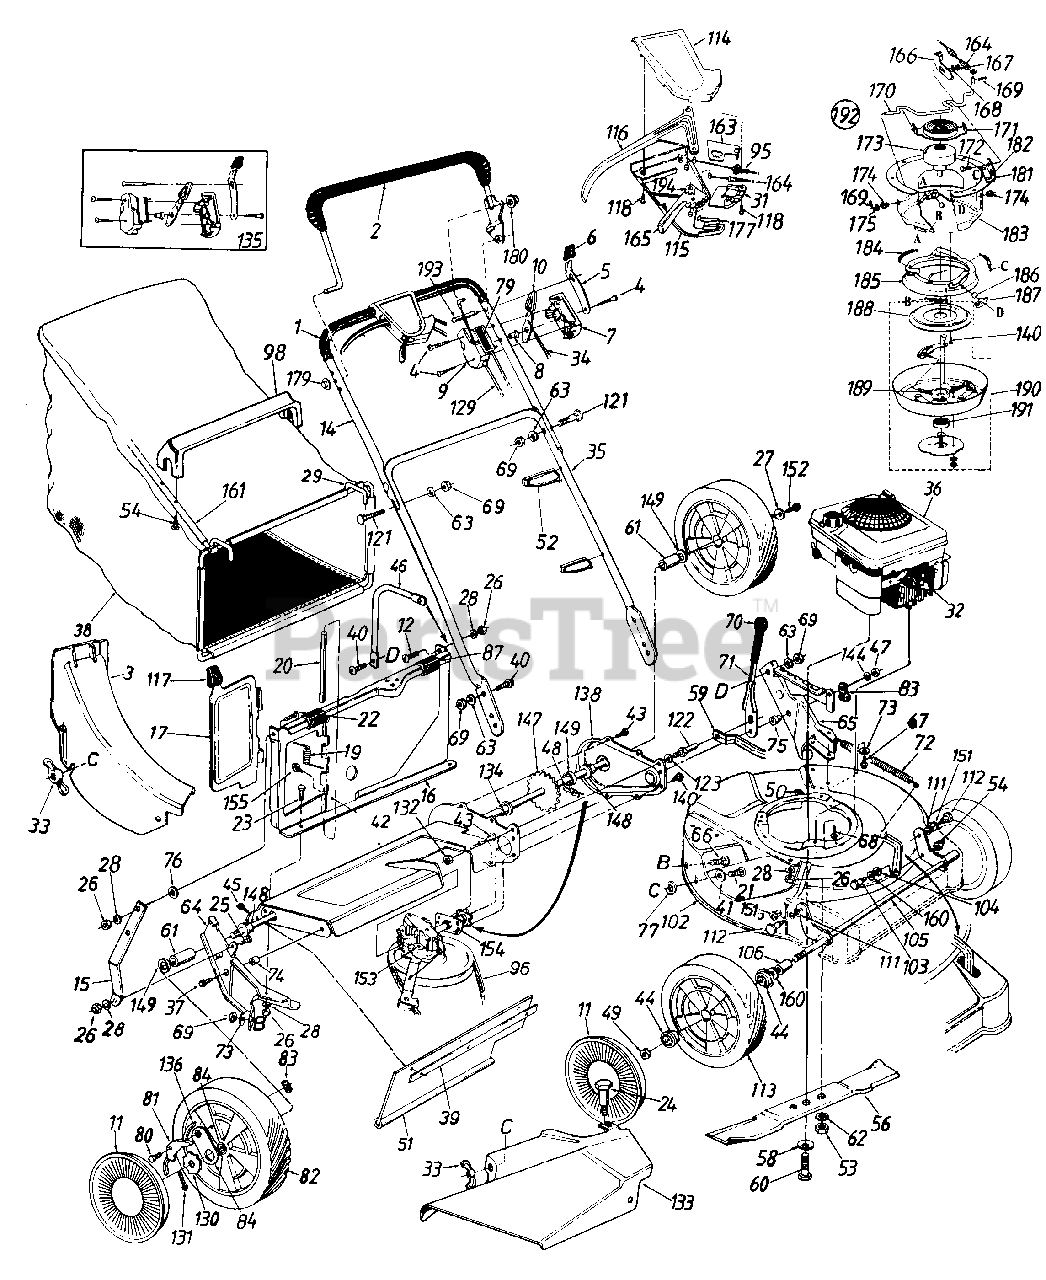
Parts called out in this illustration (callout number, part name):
1	GRIP-FOAM
3	CHUTE ASSY BLACK
4	SCREW-TRUSS MACH
5	SPRING-LOCKOUT
6	KNOB
7	PANEL HALF-CONTROL
8	PIN-CONTROL DISC
9	PANEL HALF-CLUTCH
10	LEVER-THROTTLE CONT-REV
11	HUB CAP
12	SCREW-TRUSS MACH
14	HANDLE-UPPER
19	SPRING-TORSION
21	BOLT-CARRIAGE 1/4-20 X .62
22	SCREW-TRUSS MACH
23	SCREW-HEX 1/4-20 X .50
24	SCREW-SHLD
25	SCREW-HEX 1/4-20 C .62
26	NUT-HEX 1/4-20
27	WASHER-SPRING BELL
28	LOCK WASHER 1/4 DIA
31	COVER-SP CONTROL
32	INSULATOR-SPARK PLUG
33	NUT-WING
34	WIRE-THROTTLE
35	HANDLE-LOWER PAINTED
38	BAG-GRASS-BLACK
39	STRIP-RETAINING
40	SCREW-TRUSS MACH 5/16-18 X .75
41	WASHER-FL-.344 ID X .62 OD X .033
44	BEARING-BALL
45	SCREW-HEX WASH HD
46	ARM-CATCHER SUPPORT
47	NUT-HEX LOCK 3/8-24
48	#48 CHAIN 1/2 PITCH
49	NUT-HEX INS L-1/2-20
52	TIE-CABLE
53	NUT-HEX 3/8-24
54	SCREW-HEX AB-TAP
56	BLADE-21IN
58	WASHER-BELL
59	ARM-HGT ADJ CONNECT
60	SCREW-HEX 7/16 N.F. X 2 GR.5
61	SPACER-.513 ID X .703 OD X .69
62	WASHER-LOCK-3/8
63	WASHER-LOCK-5/16
64	BRACKET ASSY-HDLE-RH
65	BRACKET ASSY-HDLE-LH
66	BOLT-CARRIAGE 5/16-18 X .62
67	SCREW-HEX WASH HD 5/16-18X1/2
69	NUT-HEX 5/16-18
71	LEVER-HGT ADJ
72	SPRING-EXTENSION
73	WASHER-BELL .337 X .867 X .057
74	SPACER
75	SPACER-SHLD .500 X .100
76	WASHER-FL-.285 ID X 1.25 OD X .060
77	RETAINER-BOLT 1/4X.50 OD
80	SCREW-SHLD .342 DIA X .268
81	PAWL
82	WHEEL ASSY W/TIRE
87	CLIP-PANEL BAG
95	CABLE-CLUTCH
96	BELT-V 3/8 X 31.0
98	HANDLE-BAG-BLACK
102	DECK ASSEMBLY-21IN
103	SCREW-SHLD .500 DIA X .295
104	WASHER-BELL .505 ID X 1.00 OD
105	AXLE ASSY
111	WASHER-INTERN L 3/8 X.56 OD X .018
112	SCREW-SHLD
113	WHEEL ASSY W/TIRE E
114	COVER-SP CONTROL-UPR
115	COVER-SP CONTROL-LWR
116	LEVER-CONTROL
117	KNOB
118	SCREW-FL C-SUNK AB
121	BOLT-CARRIAGE-CURV 5/16-18 X 1.38
122	PIN-SHLD 3/8-24X1.43 LG
123	WASHER-LOCK-3/8
129	CABLE-CLUTCH 49 IN
130	RATCHET
131	PIN-COTTER-1/8 DIA X 1.00
132	NUT-HEX JAM 3/8X24
133	DEFLECTOR-SIDE CHUTE
134	BEARING-HEX FLANGE
135	KIT-THROTTLE CONTROL
136	SPRING-NYLON
144	WASHER-FL-.385 ID X .87 OD X .06
147	SHAFT ASSY-REAR
148	BEARING-HEX FLANGE .506 ID
149	WASHER-FL-.531 X .930 OD X .050
151	BEARING-NYLINER
152	SCREW-1/4-20 X .62
153	TRANSMISSION-COMP
155	SCREW-HEX B-TAP #10 X .38
160	WASHER-FL-.510 ID X .75 OD X .033
163	BRACKET-CABLE
164	CABLE-SPEED CONTROL
165	LEVER-6 SPEED SHIFT
168	WASHER-SPRING BELL
169	PIN-COTTER-3/32 DIA X .75
170	ROD-SHIFT-LH
171	PULLEY ASSY-MOVEABLE
172	BOLT-CARRIAGE 1/4-20 X .50
173	ADAPTER-FIXED PULLEY
174	BUSHING-FLANGED
175	WASHER-FL
177	SPRING-SHIFT LEVER
179	NUT-SPEED
181	BRACKET-MTG
182	RIVET
183	HOUSING-CLUTCH
184	SPRING-EXTENSION
185	CONE-BRAKE CUP
186	BALL-STEEL
187	BALL-BLOCK
188	CONE-CLUTCH
190	GEAR CASE ASSY-COMP
191	BEARING-BALL
192	CLUTCH ASSY-BBC-COMP
193	PIN-LOCKING
194	INSERT-3 TOOTH RACK
